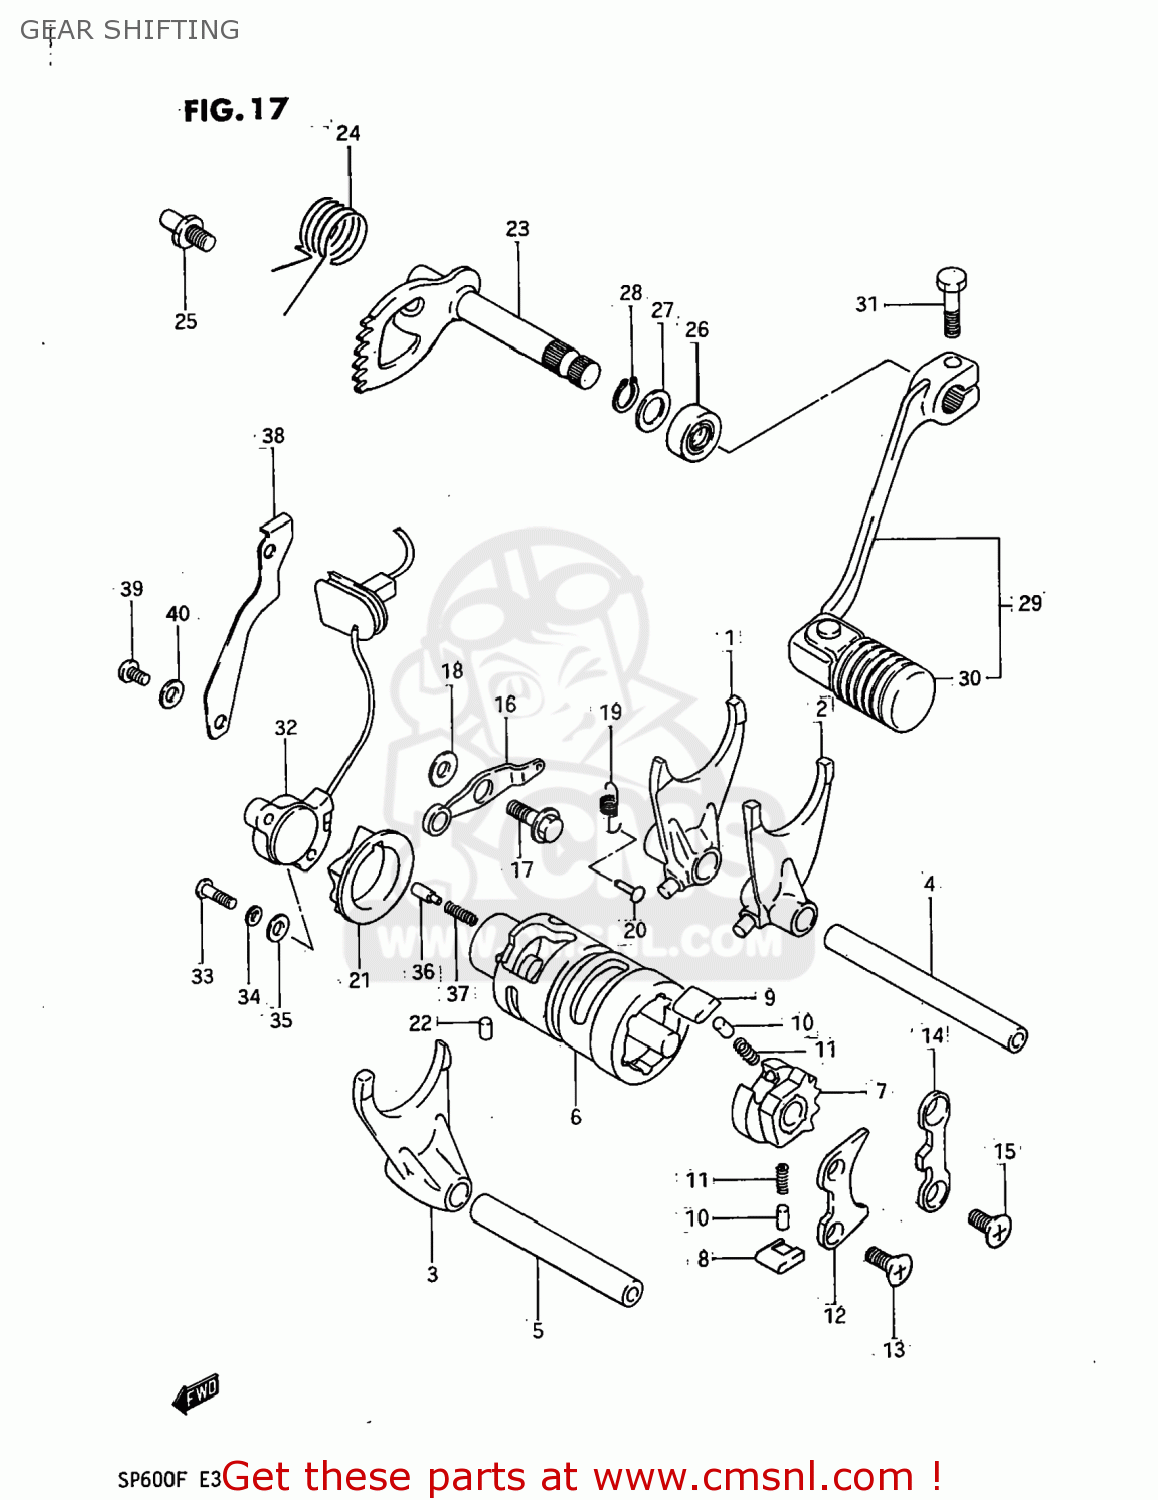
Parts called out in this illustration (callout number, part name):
1	FORK,GEAR SHIFT NO.1
2	FORK,GEAR SHIFT NO.2
3	FORK,GEAR SHIFT NO.3
4	SHAFT,GEAR SHIFT FORK
5	SHAFT,GEAR SHIFT FORK
6	CAM,GEAR SHIFT
7	GEAR,GEARSHIFT CAM DRIVE
8	PAWL,GEAR SHIFT NO.1
9	PAWL,GEAR SHIFT NO.2
10	PIN(5X8)
11	SPRING
12	LIFTER,GEAR SHAFT PAWL
13	SCREW
14	STOPPER,GEAR SHIFT POLE
15	SCREW
16	STOPPER,GEAR SHIFT CAM
17	BOLT
18	WASHER
19	SPRING
20	RIVET
21	PLATE,SHIFT CAM STOPPER
22	PIN 4X6
23	SHAFT,GEAR SHIFT
24	SPRING
25	STOPPER,GEAR SHIFT CAM
26	SEAL,OIL (12X22X9)
27	WASHER
28	CIRCLIP
29	LEVER ASSEMBLY,GEAR SHIFTING
30	RUBBER,GEAR SHIFT PEDAL
31	BOLT
32	TERMINAL BASE,NEUTRAL
33	SCREW
34	LOCK WASHER
35	WASHER
36	PIN(5X15.5)
37	SPRING
38	CLAMP,LEAD WIRE
39	SCREW
40	WASHER,LOCK
